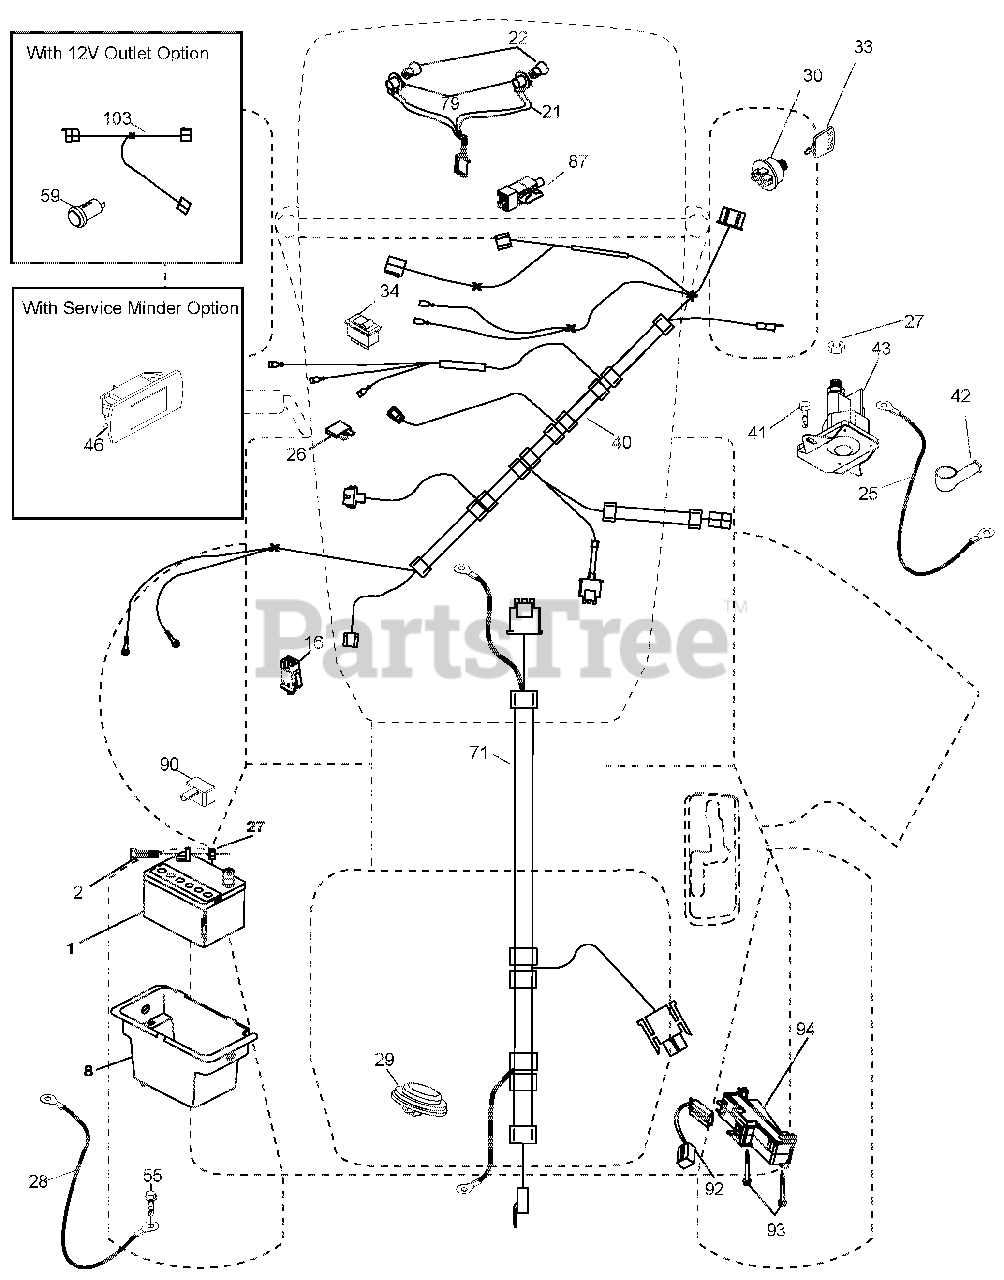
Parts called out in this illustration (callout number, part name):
1	BATTERY.12.VOLT.28.AMP.WET
2	BOLT.HEX.HD.1/4-20UNC X 3/4
8	BOX.BATTERY.MNT.REAR.LT.TEX.BL
16	SWITCH.INTERLOCK.NONO.GRAY
21	HARNESS ASM.LIGHT.22"(4152J)
22	BULB.LIGHT.#1156
25	CABLE.STARTER.6GA.BL/RED.14.5"
26	FUSE.20 AMP.
27	Nut, Keps Hex 1/4-20 unc
28	CABLE.BLACK.22"REAR BATT.TEX
29	SWITCH.SEAT.DELTA.OPC.9LB.
30	SWITCH.IGN.DLTA.P-IN.ROS
33	KEY/CHAIN.BLISTER PACK.GEN.USA
34	SWITCH.LIGHT/RESET.B/B/RED.
40	HARNESS.IGN.DASH.CBL.YTGT.PRED
41	Screw 1/4-20 x 1/2
42	COVER.TERMINAL.RED
43	SOLENOID.W/BRASS PLUNGER.2005
55	SCREW.5/16-18X3/4.SMGML.TAP/R
71	HARNESS.IGN.CHASS.TEX.REAR.BAT
79	SOCKET ASM.BULB.TWISTLOCK
87	SWITCH.INTRLCK.CLUTCH.CABLE.TX
90	COVER TERMINAL BATTERY FR. TEX
92	HARNESS.PIGTAIL.CONSLE.ROS.MLK
93	SCREW.PLASTITE.10-14 X 2.0
94	MODUAL REVERSE ROS
